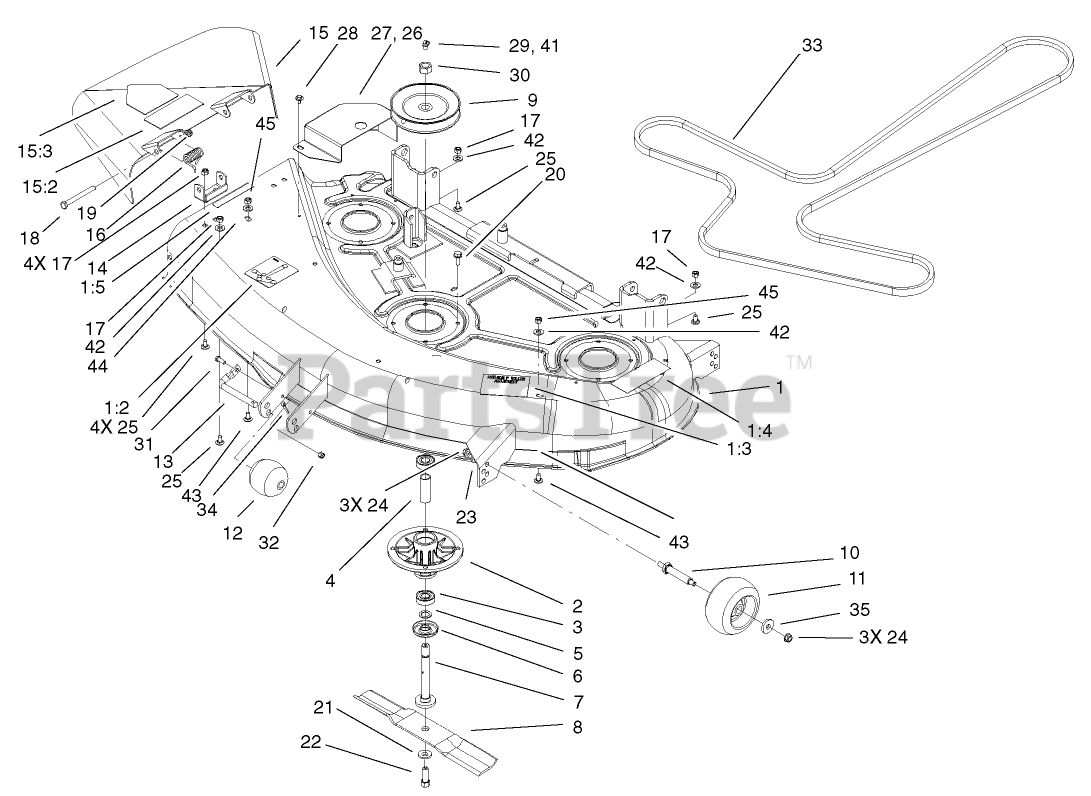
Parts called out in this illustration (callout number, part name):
1:2	DECAL-ROUTING, BELT
1:3	DECAL-ANTI SCALP
1:4	DECAL-DANGER
1:5	DECAL-DANGER
2	HOUSING-SPINDLE
3	BEARING-BALL
4	SPACER-BEARING
5	SPACER
6	SHIELD-BEARING
7	SHAFT-CENTER, SPINDLE
9	PULLEY ASM
12	ROLLER
13	SHAFT-ROLLER
14	BRACKET-PIVOT
15	DEFLECTOR ASM
15:2	DECAL-DANGER
15:3	DECAL-DANGER
16	SPRING
17	NUT-LOCK, NI
18	SCREW-HH
19	NUT-HEX
20	SCREW-TAPTITE
21	WASHER-BELLEVILLE
22	SCREW-HH
23	WASHER-BELLEVILLE
24	NUT-HHF, WHIZ
25	SCREW-CARR
26	COVER-BELT, LH
27	COVER-BELT, RH
28	SCREW-HHFTF
29	FITTING-GREASE
30	NUT-HEX
31	SCREW-HH
32	NUT-LOCK, NI
33	BELT V
34	PIN-COTTER
35	WASHER
41	FITTING-GREASE
42	WASHER-FLAT
43	SCREW-CARR
44	WASHER-FLAT
45	NUT-LOCK, NI
